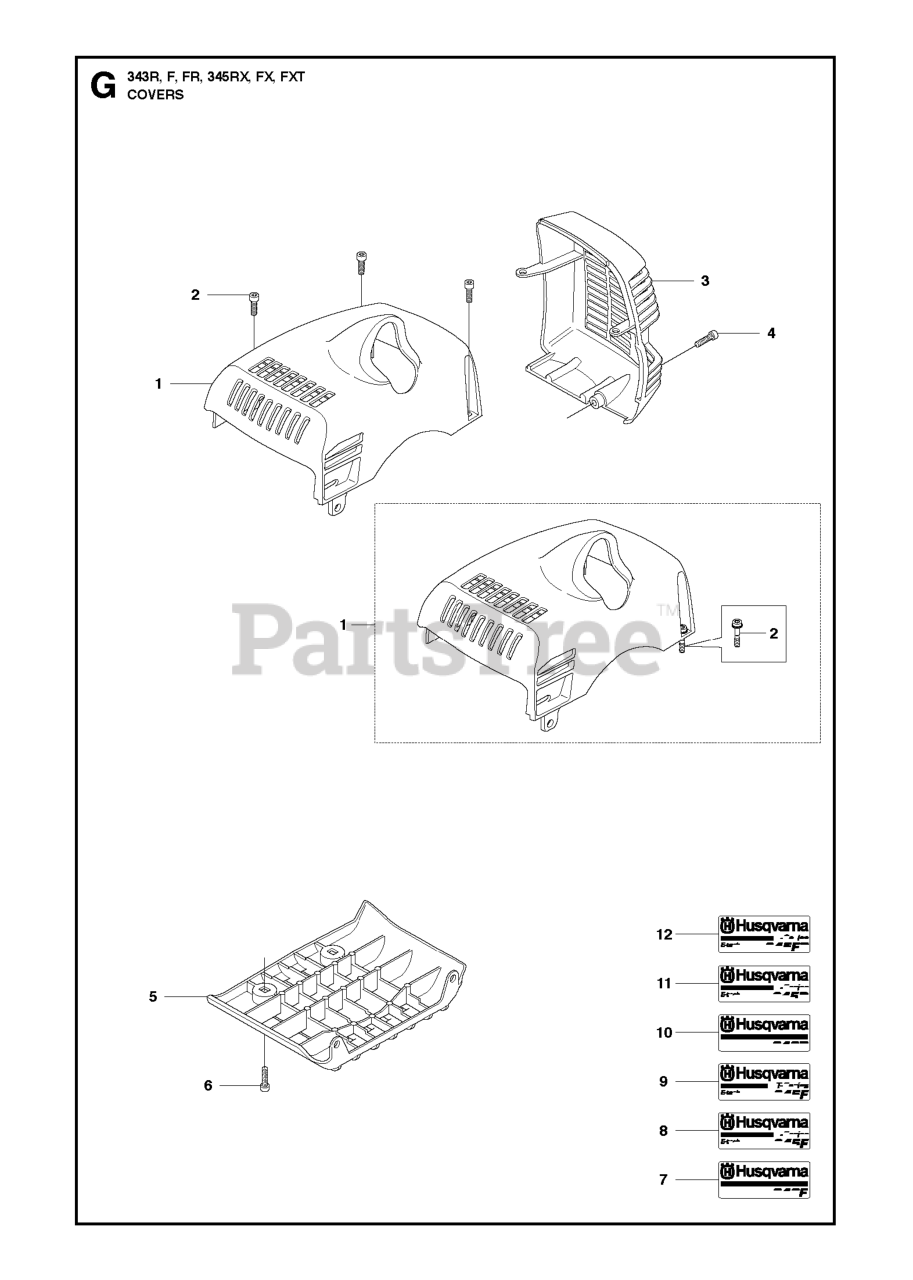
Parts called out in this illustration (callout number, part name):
1	CYLINDER COVER ASSY
1	CYLINDER COVER
2	SCREW IHSCFM
2	SCREW IHSCFMO
3	MUFFLER COVER
4	SCREW IHSCFM
6	SCREW IHSCFM
7	LABEL
8	DECAL
9	DECAL
10	DECAL
11	DECAL
12	LABEL
